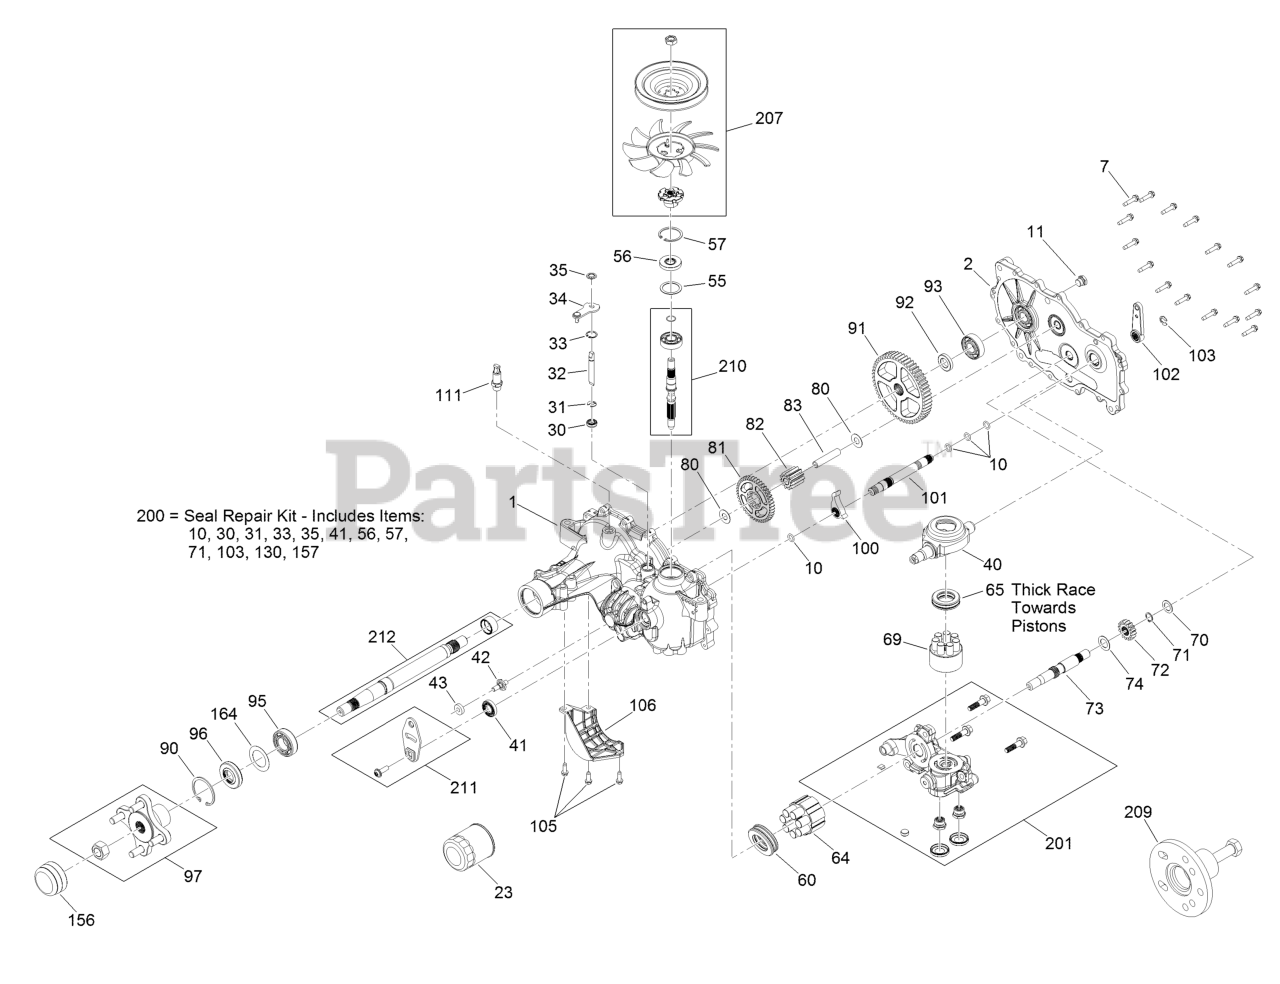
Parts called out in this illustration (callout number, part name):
1	Main Housing Kit
2	RH Side Cover Kit
7	Screw-HHF
11	Plug-Straight
23	Element-Oil Filter, HYD
30	Seal-Lip
31	Ring-Retaining, External
32	Rod-Bypass
33	Ring-Retaining, Internal
34	Arm-Bypass
35	Ring-Retaining, External
40	Swashplate-Trunnion
41	Seal-Lip
43	Puck-Friction
56	Seal-Lip
57	Ring-Retaining
60	Bearing-Thrust
64	Motor Cylinder Block Kit
65	Bearing-Thrust
69	Pump Block ASM
70	Washer-Flat
71	Ring-Retaining
72	Gear-16T
73	Shaft-Motor
80	Washer
81	Gear-43T
82	Gear-11T
83	Pin-Jackshaft
90	Ring-Retaining
91	Gear-54T
93	Bearing Kit
95	Input Bearing Kit
96	Seal-Lip
97	Hub Kit
100	Pawl-Brake
101	Shaft-Brake, Inboard
102	Handle-Brake
103	Ring-Retaining, EXT
106	Guard-Filter, RH
111	Adapter-Straight
156	Cover-Nut, Axle
200	Seal Kit
201	RH Center Section Kit
207	Fan Pulley Kit
209	Puller-Hub, 4 Bolt
210	Input Shaft Kit
211	Control Arm Kit
212	Axle Shaft Kit
